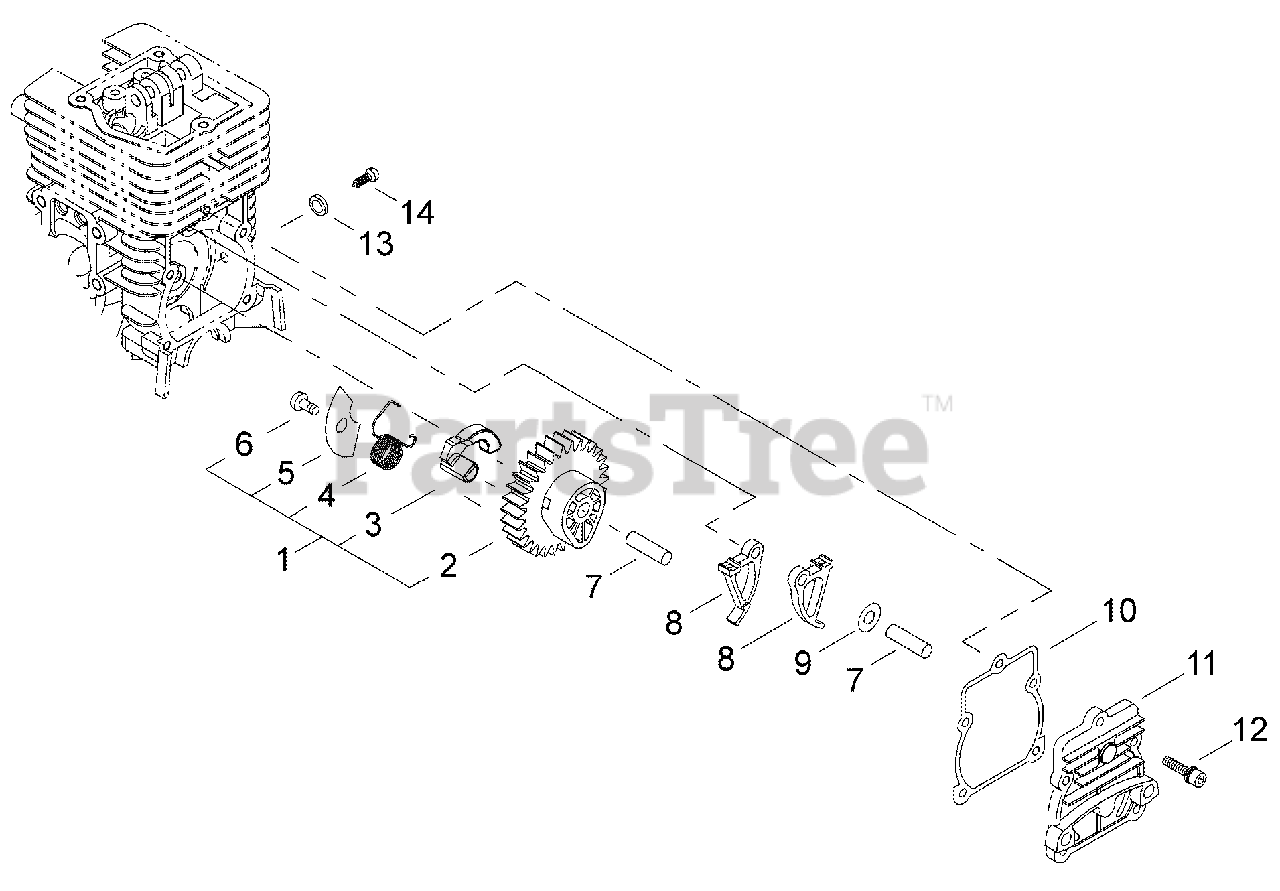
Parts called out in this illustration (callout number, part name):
1	CAM GEAR ASSY
2	GEAR, CAM
3	WEIGHT
4	SPRING
5	PLATE, COVER
6	SCREW, TAPPING 4×6
7	PIN, LOCATING Ø5×29.8 MM
8	FOLLOWER, CAM
9	WASHER 5 MM
10	GASKET, CAM GEAR
11	COVER, CAM GEAR
12	BOLT M4×14
13	WASHER Ø10ר5.5×2
14	SCREW M5
